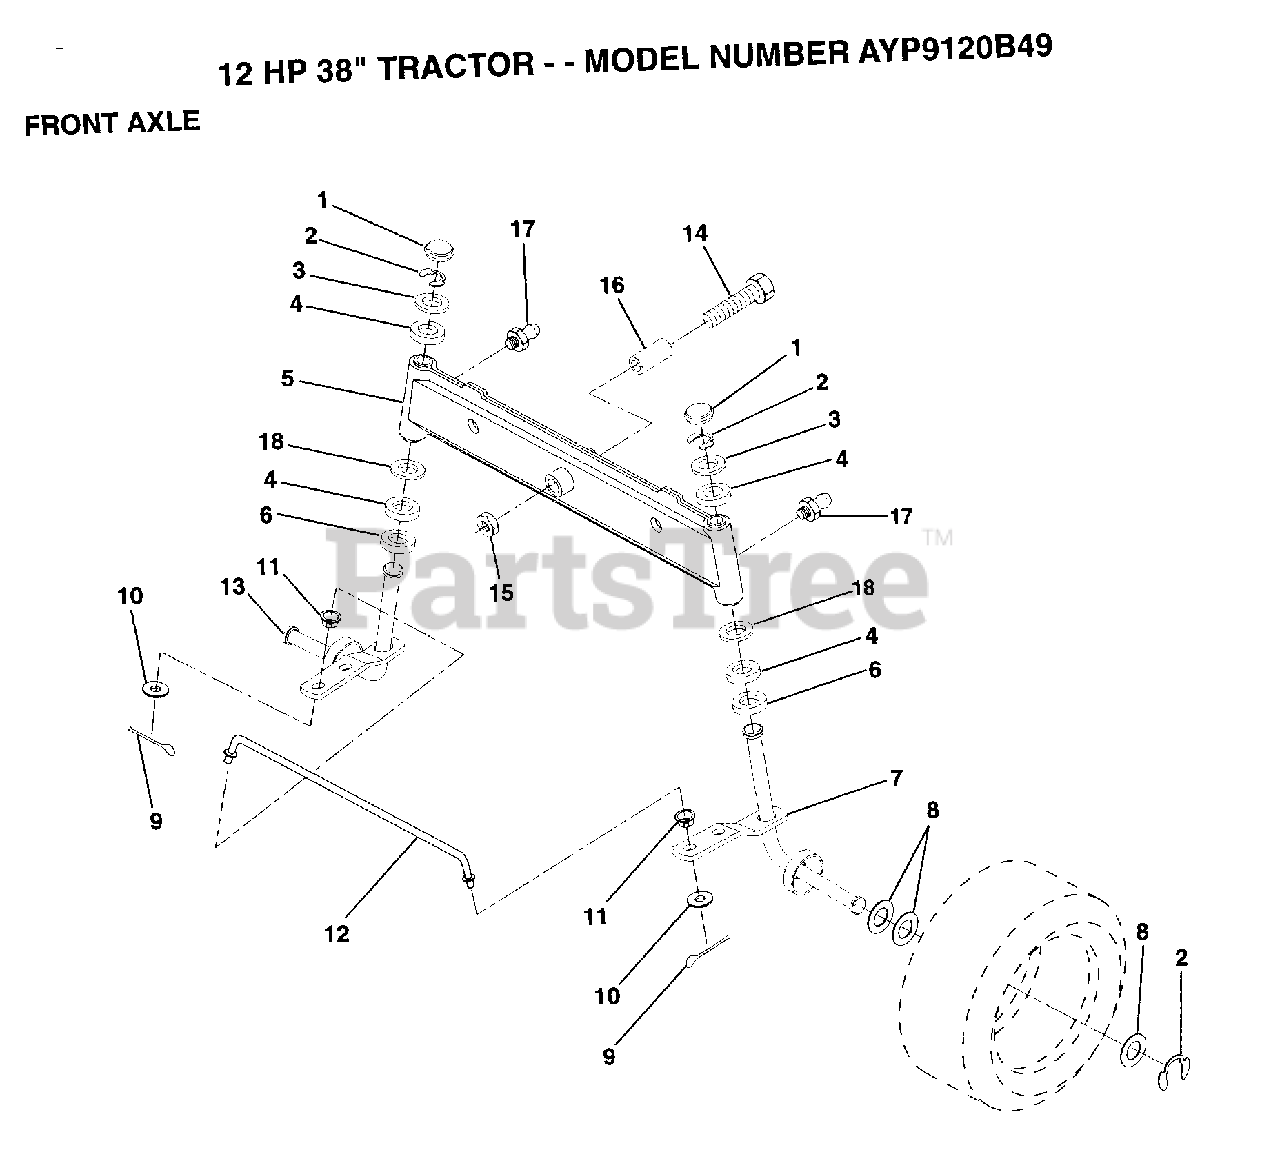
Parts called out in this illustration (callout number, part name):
1	CAP
2	RING
3	WASHER
4	COL. SRTG. BEAR.
5	AXLE ASM FRONT
6	WASHER .T
7	SPINDLE ASM RH
8	WASHER
9	COTTER PIN
10	WASHER
11	BUSHING.DRAGLINK
12	TIE ROD
13	SPINDLE ASM LH
14	BOLT HEX 5/8-11
15	"NUT-LOC,FLANGE LT"
16	BEARING
17	ZERK M
18	WASHER
